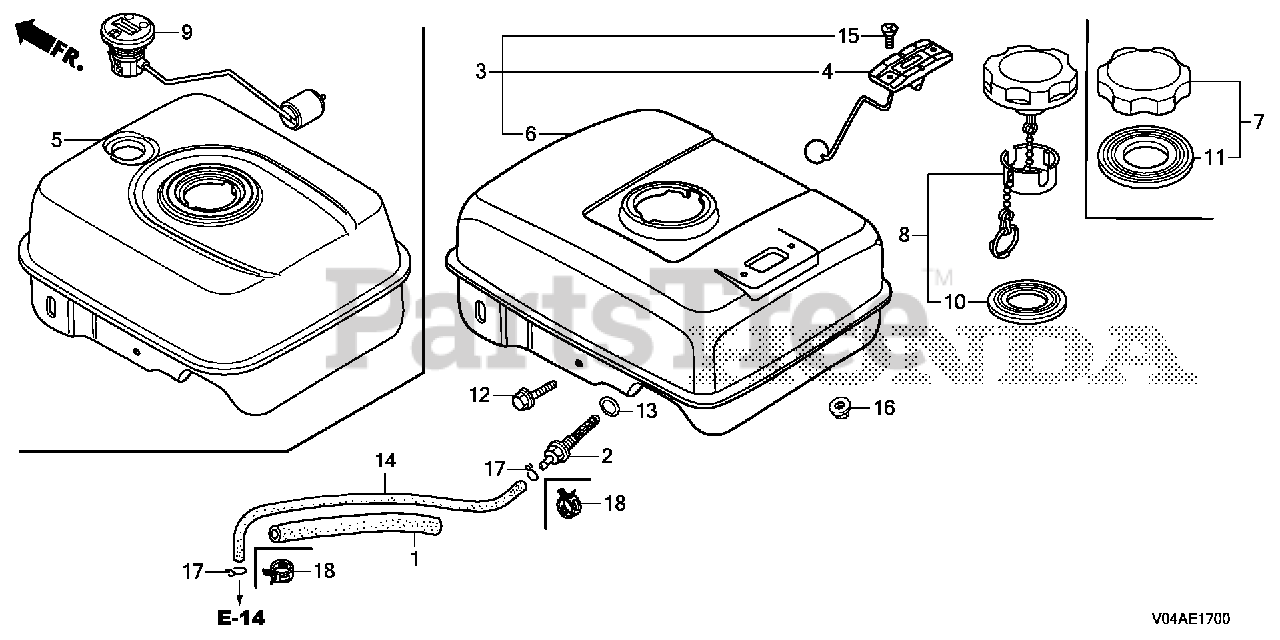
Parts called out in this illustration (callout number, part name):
1	RUBBER, SUPPORTER (107MM)
2	JOINT, FUEL TANK
5	TANK, FUEL *R280* (POWER RED)
8	CAP, FUEL FILLER
10	GASKET, FUEL FILLER CAP
10	GASKET, FUEL FILLER CAP (39X62X3) (TOUYOUSYA)
12	BOLT, FLANGE (6X34)
13	O-RING (14MM) (ARAI) Use up to Engine SN 2949254.
14	TUBE, FUEL (4.5X145) (FKM)
16	NUT, FLANGE (6MM)
18	CLIP, TUBE (D8)
